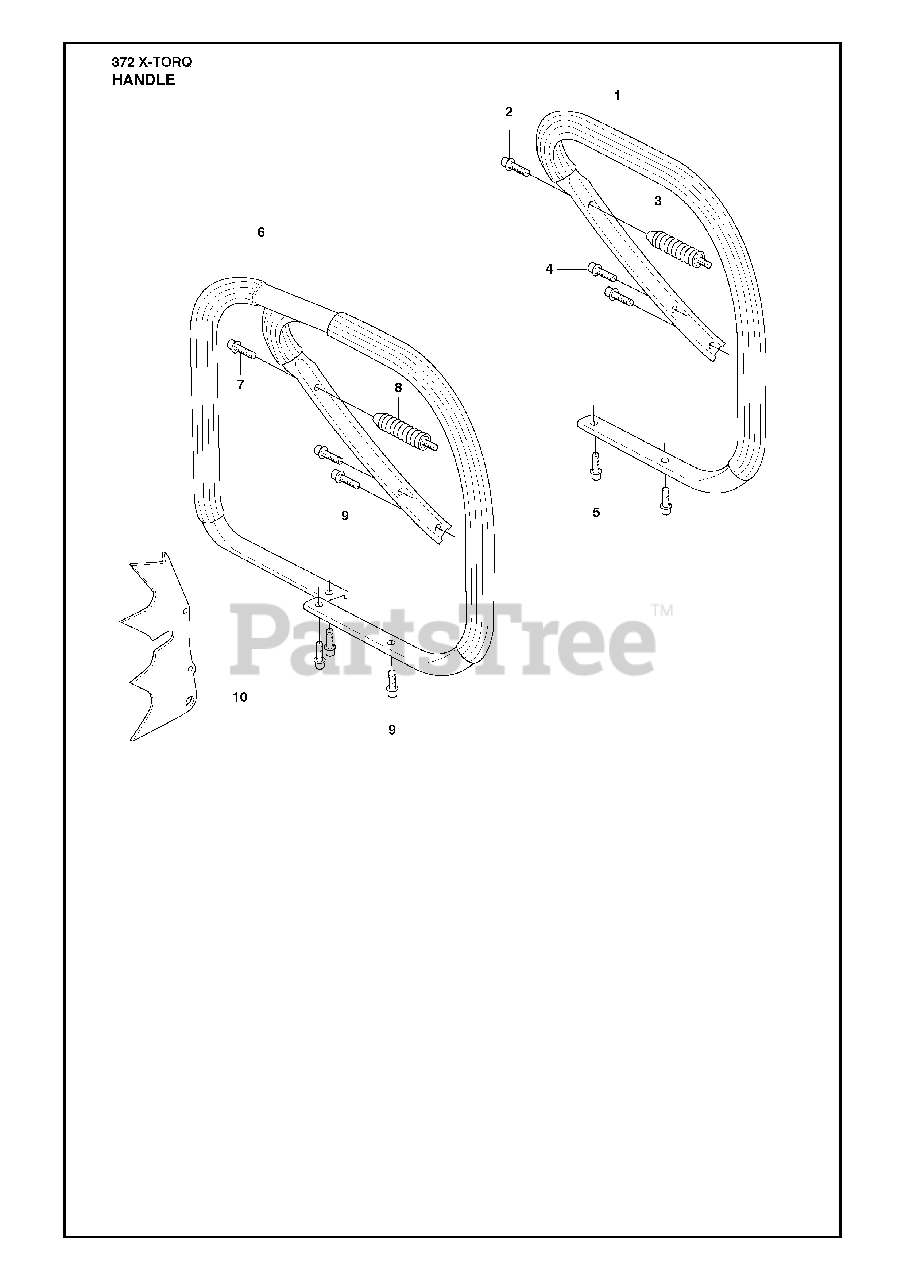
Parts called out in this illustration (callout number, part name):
1	FRONT HANDLE ASSY
3	ANTIVIBE MOUNT
3	VIBRATION ABSORBER
4	SCREW
5	SCREW
6	FRONT HANDLE ASSY
8	ANTIVIBE MOUNT
9	SCREW
10	FELLING DOG
